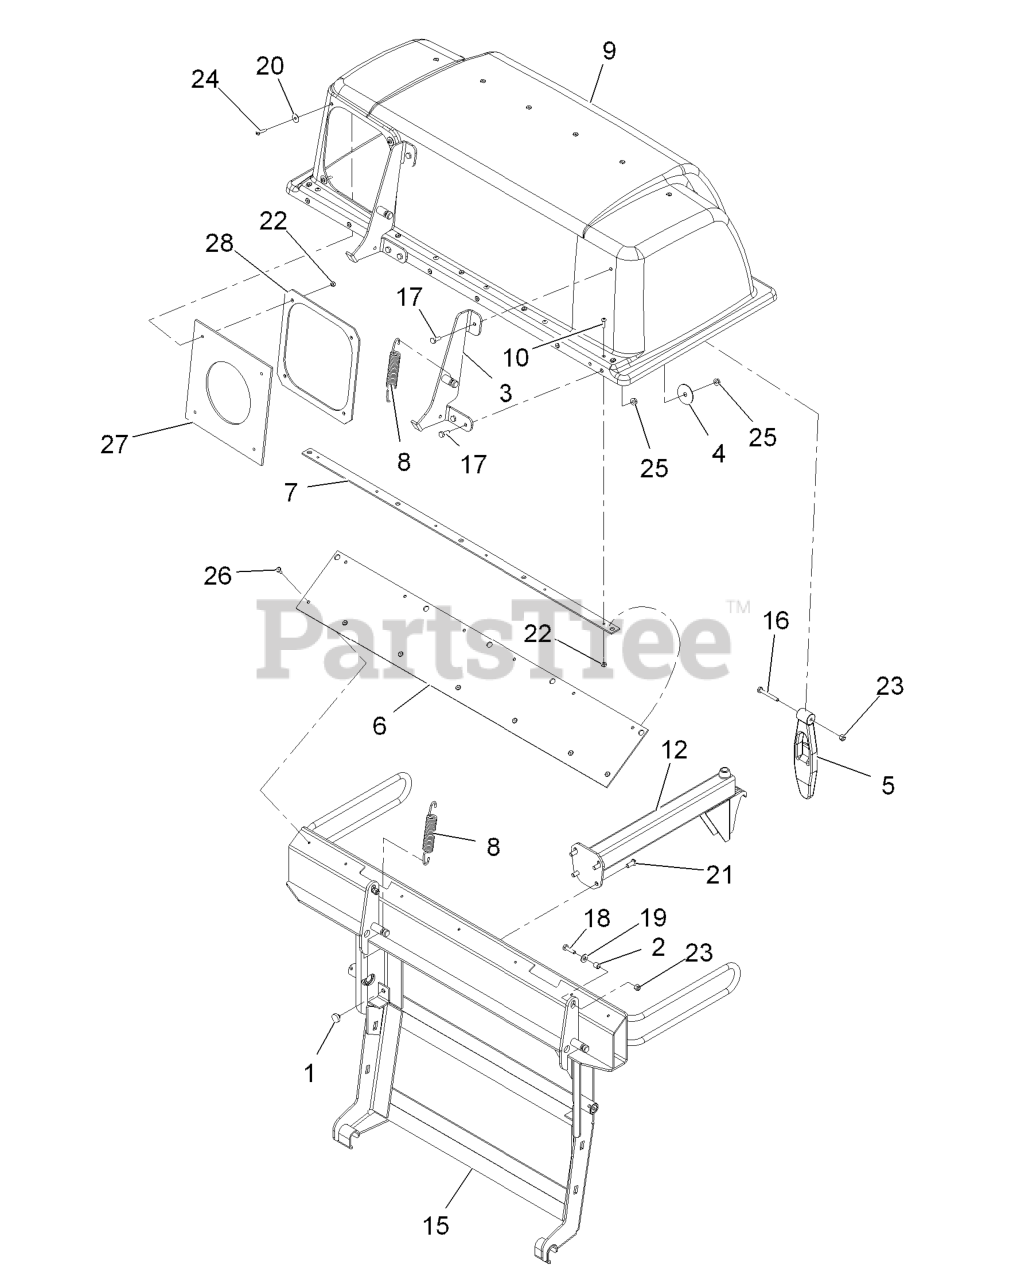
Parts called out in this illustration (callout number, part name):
3	HINGE ASM
7	PLATE-BACKING
8	SPRING-EXTENSION
9	ASM, HOOD
10	SCREW-HEAD, TRUSS
12	BAG SUPPORT ASM
15	FRAME-BAG, TWIN
16	SCREW-HH
17	SCREW-HH
18	SCREW-HH
19	WASHER-FLAT
20	WASHER-FLAT
21	SCREW-HSBH
22	NUT-LOCK, NI
23	NUT-LOCK, NI
24	SCREW-PPH
26	RIVET-BLIND
27	SEAL-CHUTE
28	CLAMP-SEAL
